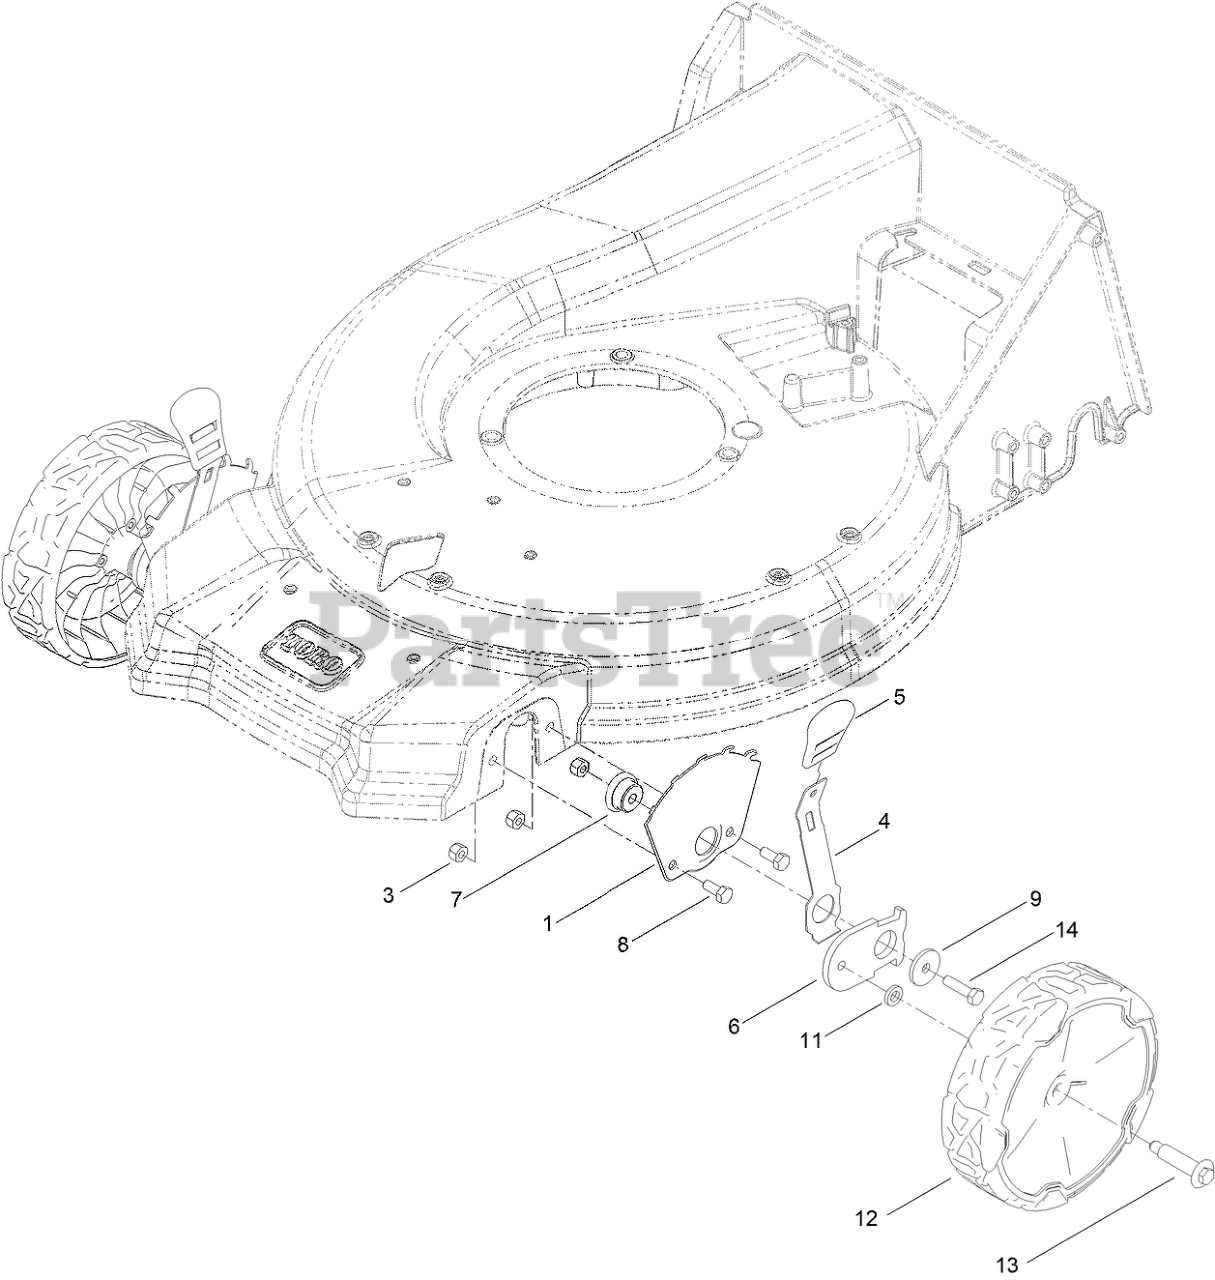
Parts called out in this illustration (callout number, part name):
1	PLATE-HOC,FRONT FSVQ WEDNESDAY
3	NUT-HEX
4	ARM-SPRING
5	KNOB-HOC
6	ARM-PIVOT, FRONT
7	BUSHING-MOUNT, HOC
8	SCREW-HH
9	WASHER-FLAT
11	WASHER-WHEEL BOLT
12	ASM-WHEEL, 8" (BEARINGS)
13	WHEEL BOLT
14	SCREW-HH
